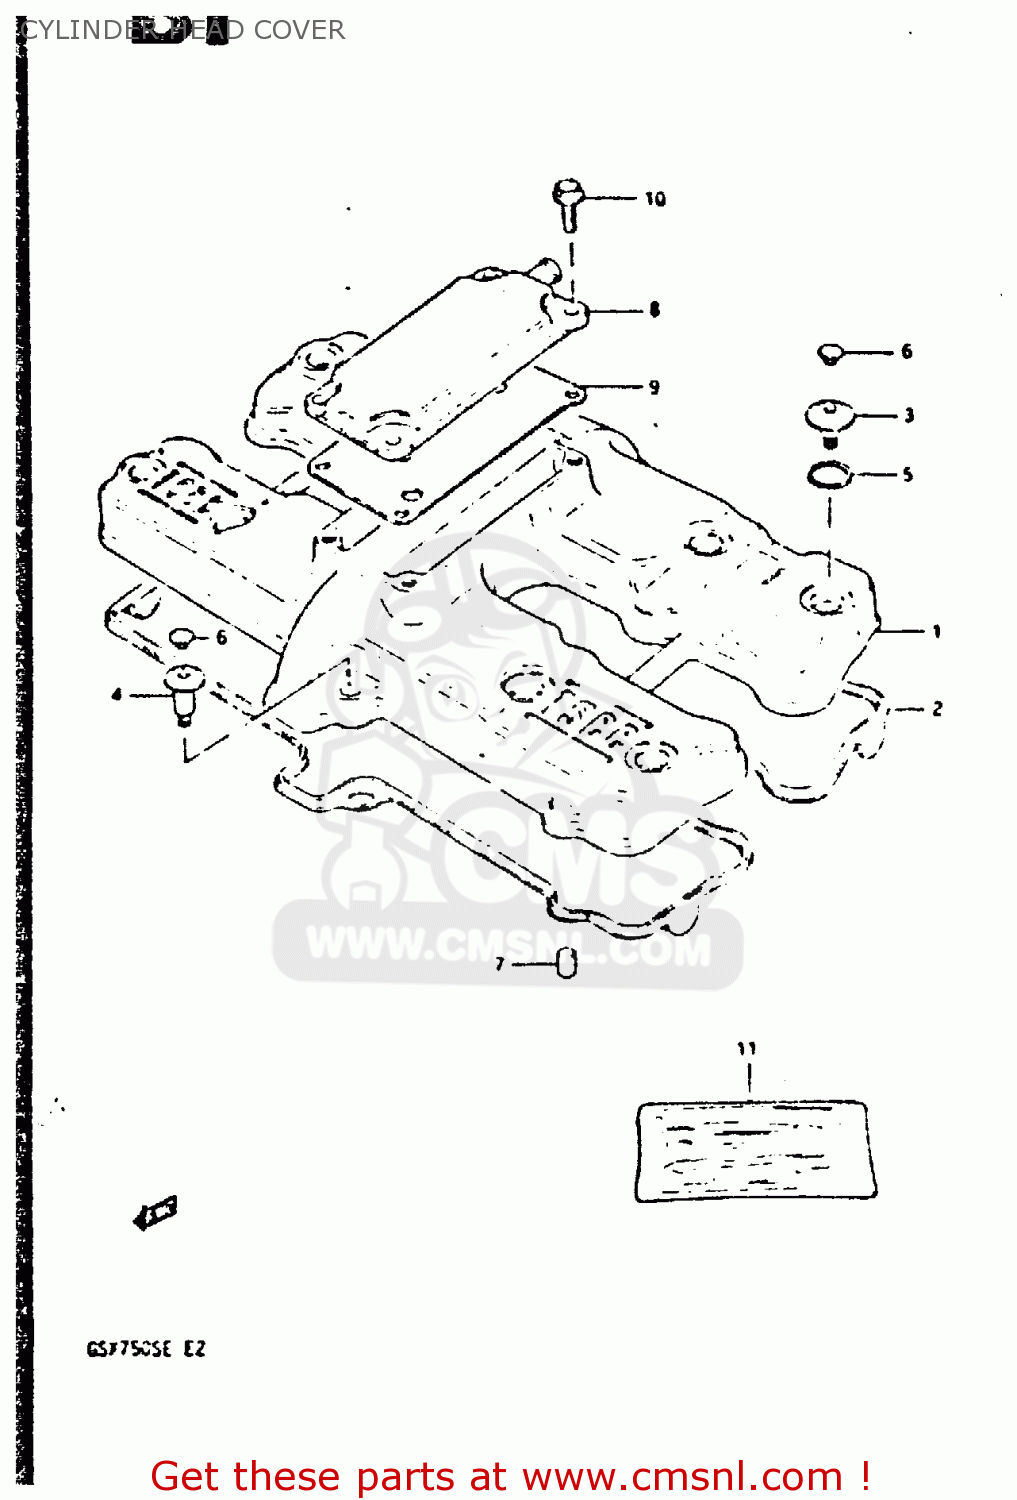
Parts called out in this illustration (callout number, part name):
1	COVER, CYLINDER HEAD
2	GASKET,HEAD COVER (NAS)
3	BOLT(7X5.5)
4	BOLT(7X19)
5	WASHER
6	CAP(OD:10)
7	PIN
8	COVER,BREATHER
9	GASKET (MCA)
10	BOLT,REAR
11	GASKET SET
